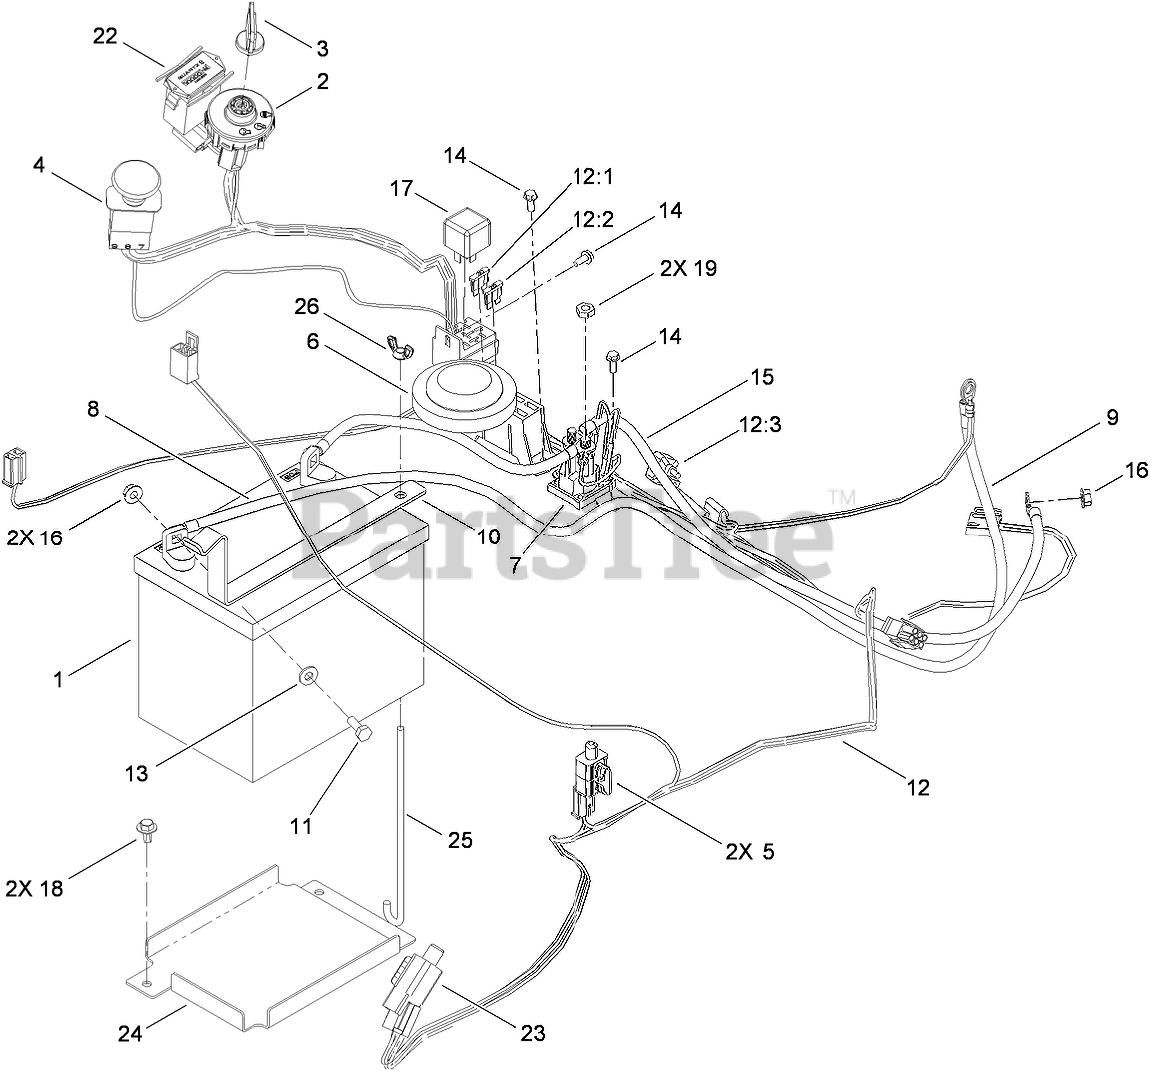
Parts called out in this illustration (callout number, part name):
1	BATTERY
2	SWITCH-IGNITION
3	KEY-IGNITION
4	SWITCH-PTO
5	SWITCH
6	SWITCH-SEAT
7	SOLENOID
8	CABLE-BATTERY, POSITIVE
9	CABLE-BATTERY, NEGATIVE
10	STRAP-BATTERY
11	SCREW-HH
12	Harness-Wire
12:1	FUSE-BLADE, 30 AMP
12:2	FUSE-BLADE, 25 AMP
13	WASHER-FLAT
14	SCREW-TAPTITE
15	WIRE-21 INCH
16	NUT-HF
17	RELAY
18	SCREW-HHFTF
19	NUT-JAM
22	METER-HOUR
23	SWITCH-REVERSE
24	TRAY-BATTERY
25	BOLT-HOLDDOWN
26	WINGNUT
